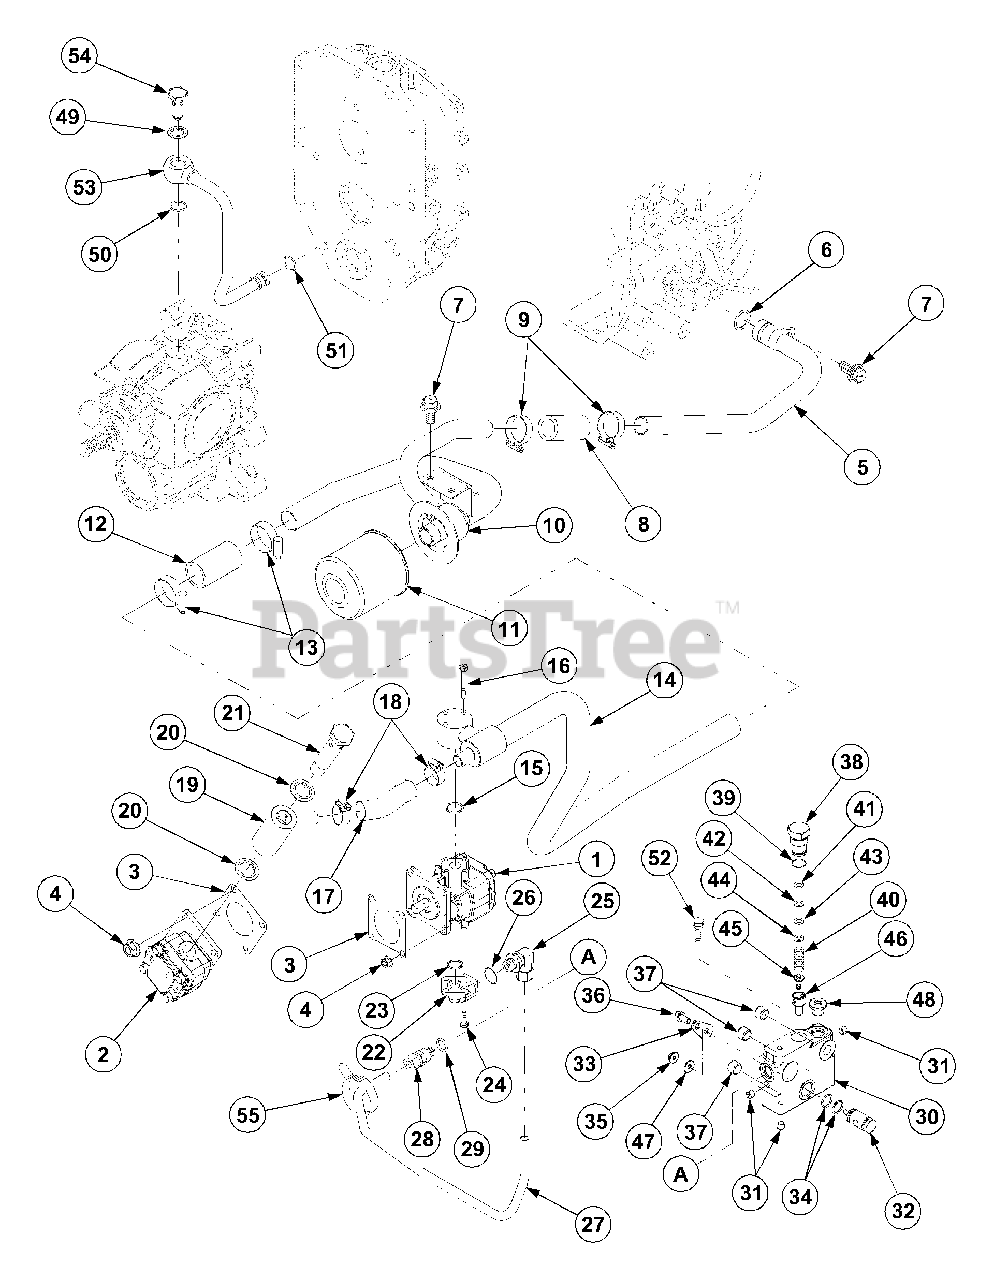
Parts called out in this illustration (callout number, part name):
1	Pump,Hydraulic
5	Pipe A,Suction
7	Bolt,w/Washer
10	Pipe B,Suction
14	Pipe C,Suction
16	Bolt,w/Washer
24	Bolt,w/Washer
25	Elbow
27	Pipe B,Pressure
28	Nipple
36	Bolt,w/Washer
52	Bolt,w/Washer
53	Pipe,Return HST
55	Band,Wire
